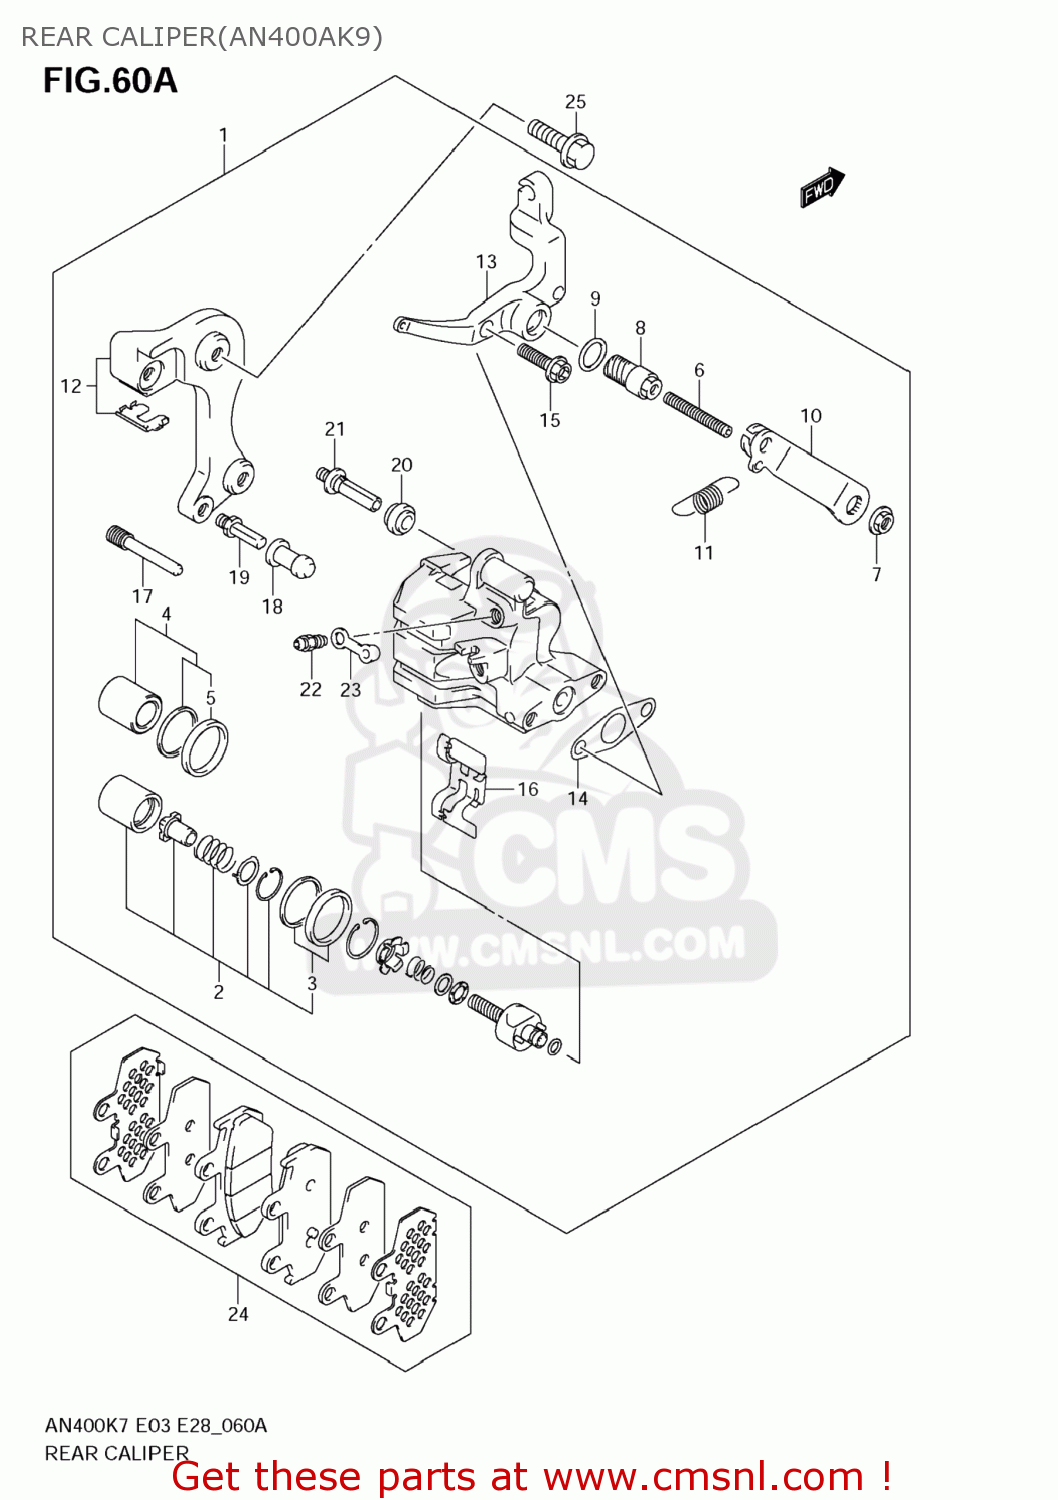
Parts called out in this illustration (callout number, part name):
1	CALIPER ASSY,RR
2	PISTON SET
3	SEAL SET,PISTON
4	PISTON SET
5	SEAL SET,PISTON
6	BOLT
7	NUT
8	SHAFT
9	O RING
10	ARM
11	SPRING,RETURN
12	BRACKET,RR
13	PARKING
14	PACKING (NAS)
15	BOLT(8X25)
16	SPRING,PAD
17	PIN,HANGER
18	BOOT
19	PIN,BOLT
20	BOOT
21	PIN
22	BLEEDER
23	CAP,BLEEDER
24	PAD & SHIM SET (NAS)
25	BOLT
